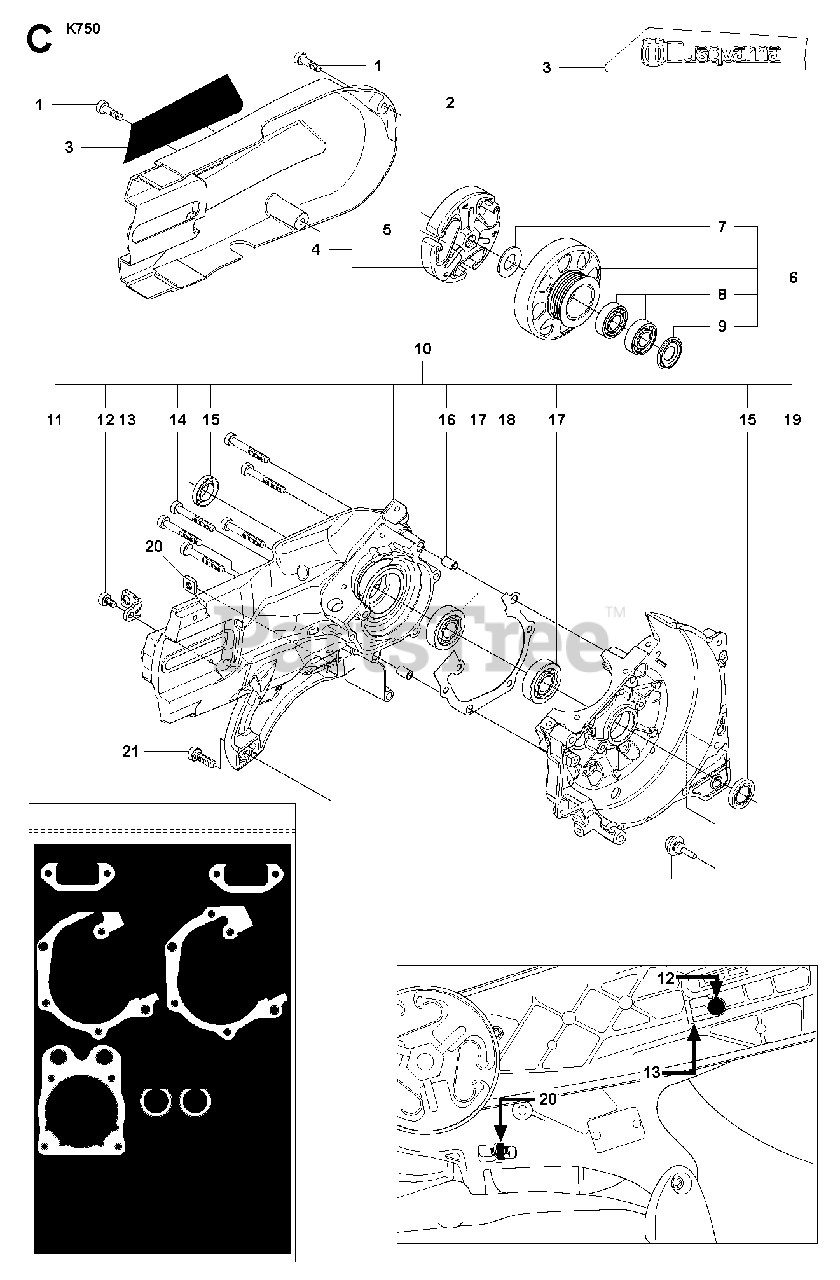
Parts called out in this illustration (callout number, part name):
1	SCREW ITXSCM
2	BELT GUARD
4	CLUTCH ASSY
5	CLUTCH SPRING
6	DRIVING PULLEY ASSY
7	WASHER
8	BALL BEARING
10	CRANKCASE ASSY
11	GASKET KIT
12	SCREW IHSCFM
14	SCREW ITXSCM
15	SEALING RING
16	GUIDE BUSHING
17	BALL BEARING
21	SCREW ITXSCM
23	GASKET
27	GASKET
